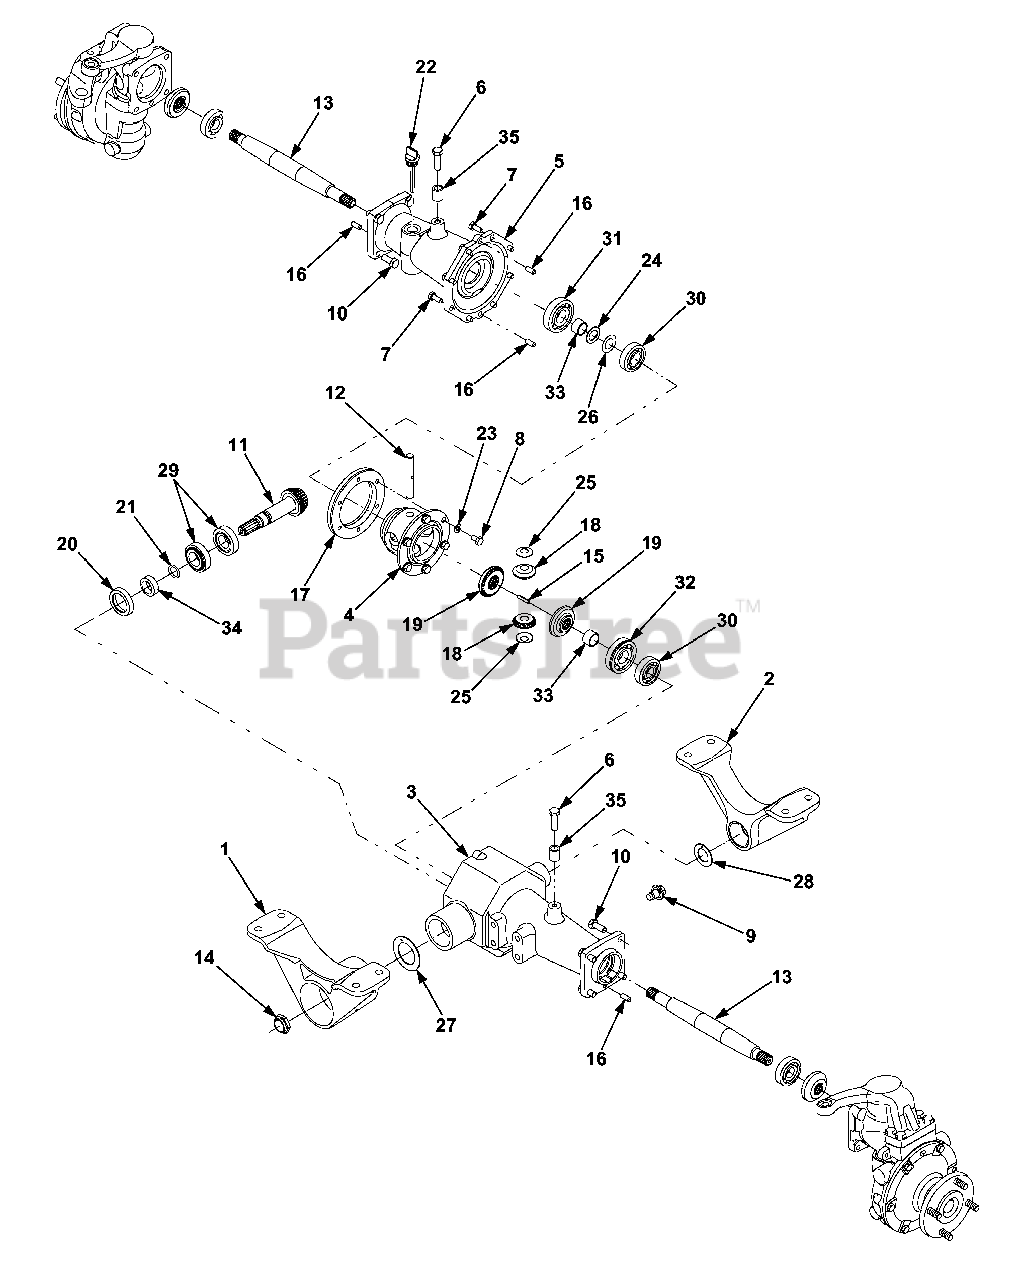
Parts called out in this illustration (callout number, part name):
1	Bracket, Front Axle Mtg. - Rear
2	Bracket, Front Axle Mtg. - Front
3	Housing, Main Axle RH
4	Housing, Differential
5	Housing, Axle LH
6	Screw, Hex Cap, M10-1.5 x 35 GR8.8
7	Screw, Hex Cap, M8-1.25 x 20 GR8.8
8	Screw, Hex Cap, M8-1.25 x 14 GR8.8
9	Plug, Screw, M14-1.5 x .827
10	Screw, Hex Cap, M10-1.5 x 25
11	Shaft, Input, 11T
12	Shaft, Cross
13	Shaft, Axle
14	Nut, Special, 24mm
15	Pin, Roll, 5mm x 26mm
16	Pin, Dowel, 8mm x 20mm
17	Gear, Bevel, 35T
18	Gear, Miter, 10T
19	Gear, Miter, 16T
20	Seal, Oil, 52mm x 35mm x 10mm
21	O-Ring, 19mm x 3mm
22	Dipstick, Front Axle
23	Washer, Flat, .33 x .63 x .0635
24	Washer, Flat, .793 x 1.24 x .06 Hdn.
25	Washer, Special Spherical
26	Washer, Flat, .793 x 1.37 x .005
27	Washer, Thrust, 1.66 x 2.59 x .059
28	Washer, Thrust, 1.03 x 1.73 x .059
29	Bearing, Tapered Roller w/ Race
30	Bearing, Ball
31	Bearing, Ball
32	Bearing, Ball
33	Spacer, 20 x 25 x 16mm
34	Spacer, 25 x 35 x 12mm
35	Spacer, .5 x .75 x .86
